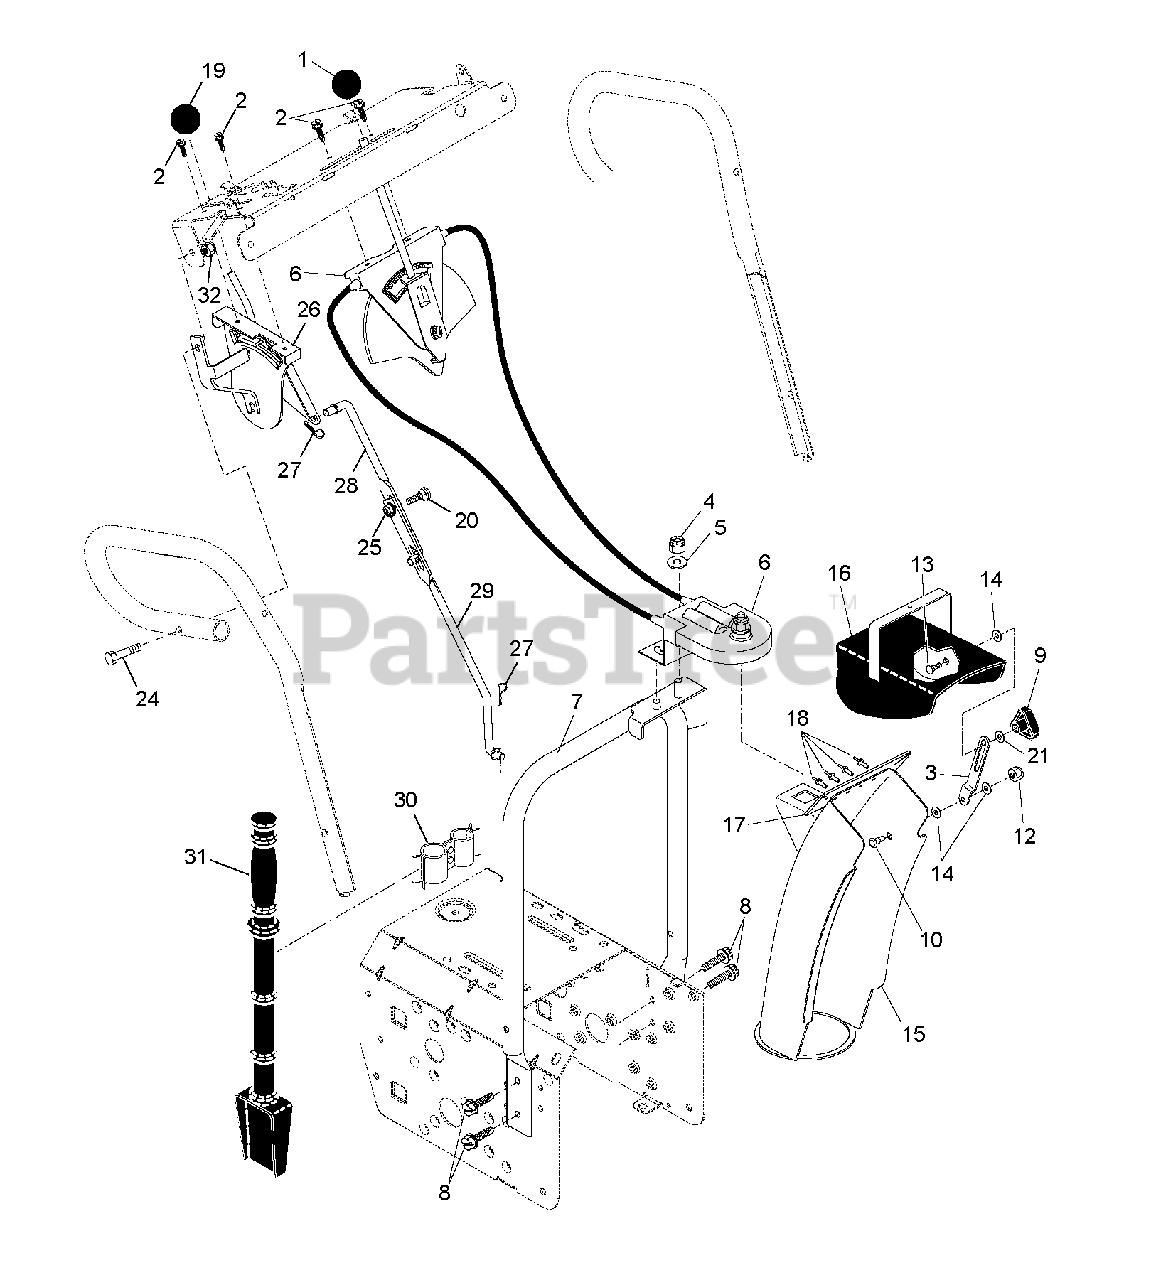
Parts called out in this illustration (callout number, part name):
1	KNOB, LEVER
2	SCREW #10-24 X 5/8
3	STRAP, CHUTE
4	NUT
6	CONTROL ASSEMBLY,CHUTE ROTATER
7	SUPPORT, PIVOT
8	SELF-TAPPING SCREW 5/16-18X3/4
9	KNOB, DEFLECTOR
10	SHOULDER BOLT
12	NUT.HEX.FLANGE.1/4
13	BOLT
14	WASHER, NYLON FRICTION
17	SEAL, DEFLECTOR
18	RIVET BLIND
19	RP KNOB, SPEED CONTROL LEVER
21	WASHER.20X8.5
25	NUT, HEX FLANGE 5/16-18
26	HEAD ASSY SPEED
27	SPRING RETAINER
28	ROD, UPPER SPEED CONTROL
29	ROD, LOWER SPEED CONTROL
30	CLAMP.ASM.CLEANOUT.TOOL.SNOW
31	CLEAN OUT TOOL
32	NUT, LOCK 5/16-18
